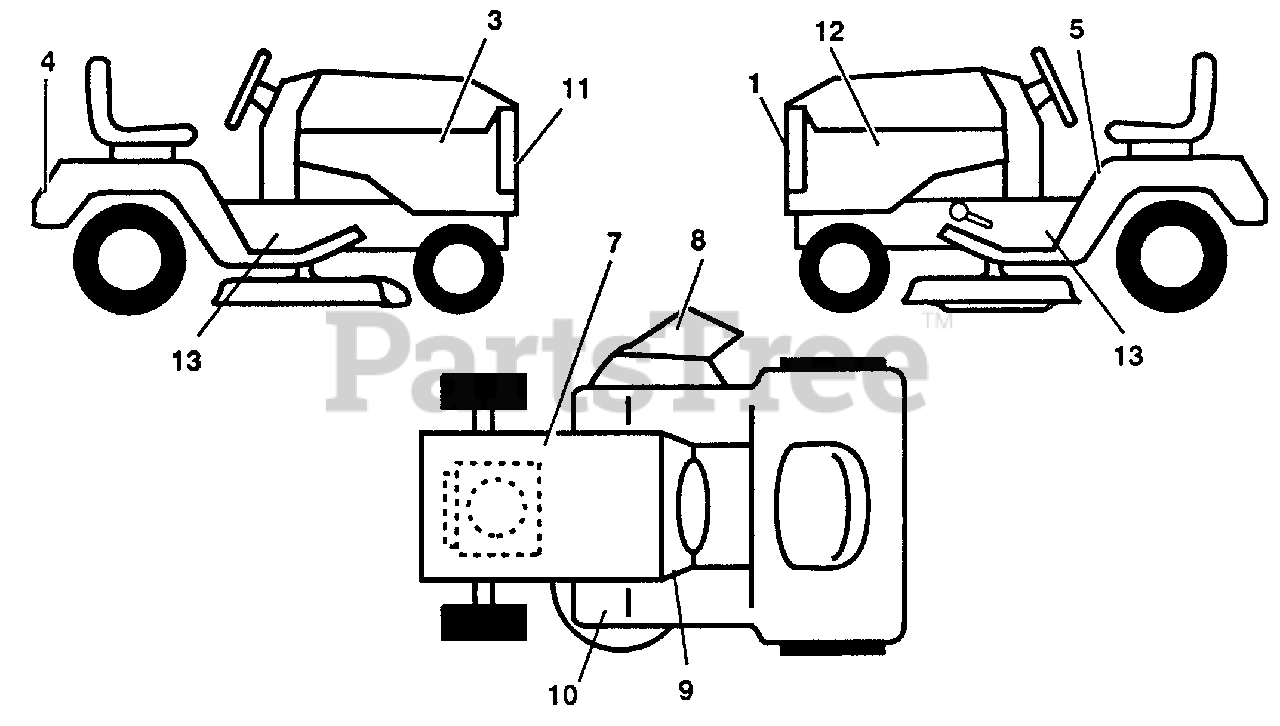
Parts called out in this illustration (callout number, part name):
1	Decal, Logo, Grill
3	Decal, Hood, RH
4	Decal, Logo, Fender
5	Decal, Caution, (English/French)
7	Decal, Caution, Battery
8	Decal, Caution, Deflector, (English/French)
9	Decal, Operating Instructions, (English/French)
10	Decal, Clutch/Brake (English/French)
11	Decal, Belt Adjustment PTO (English/French)
12	Decal, Hood LH
13	Decal, Chassis
